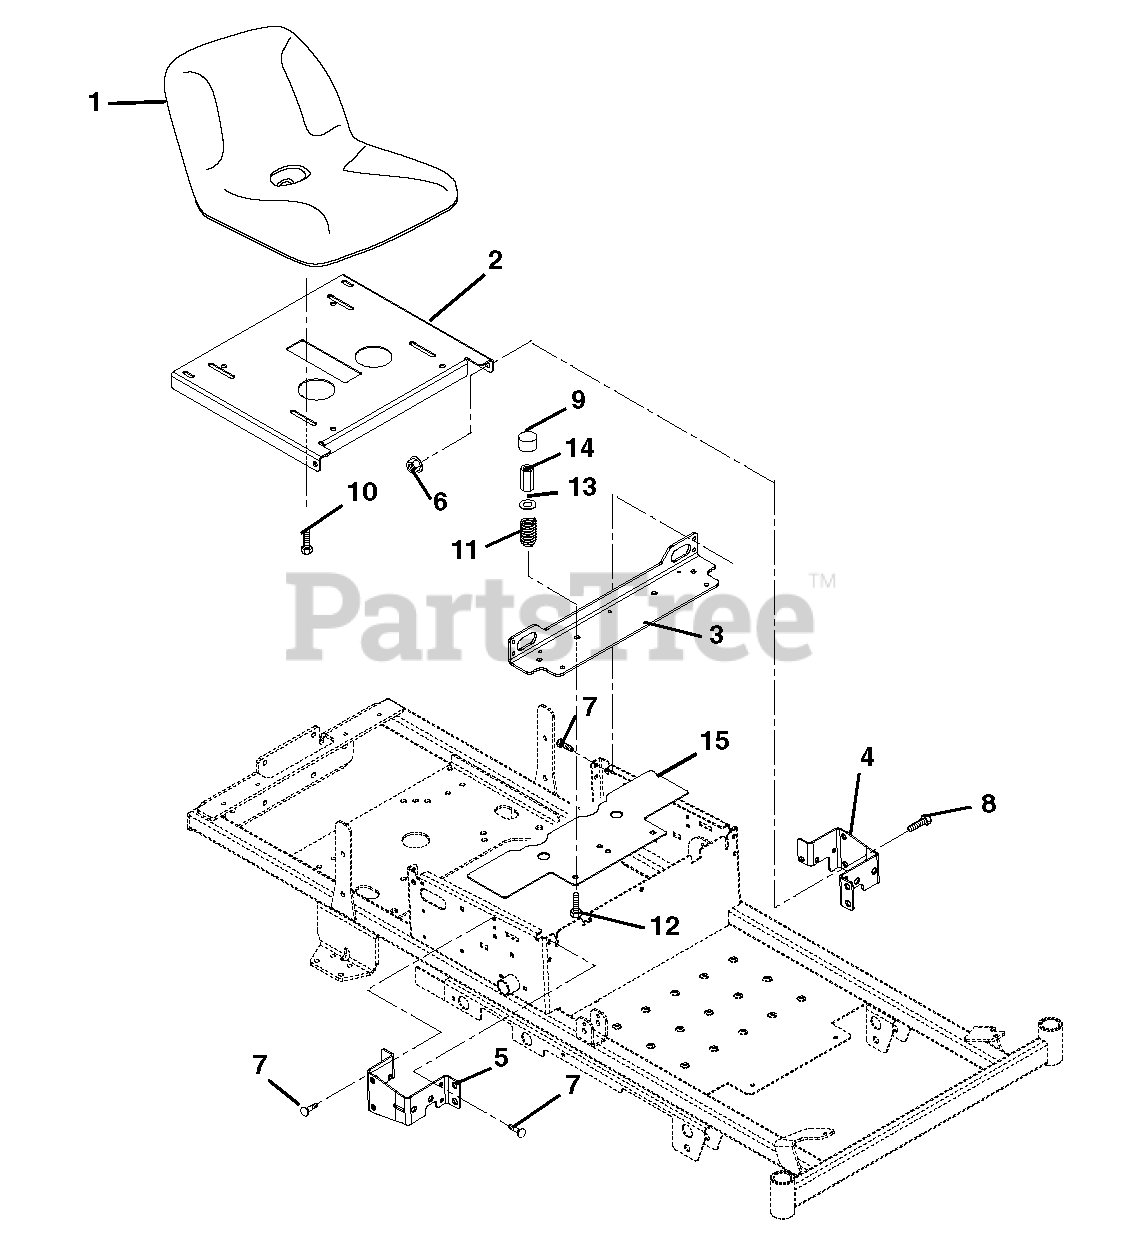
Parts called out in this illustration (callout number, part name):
1	Seat, Milsco XB150 Gray (100 - Serial No. 1148 and up; 102 - Serial No. 1013 and up; 104 - Serial No. 663 and up, 132 - Serial N
2	Seat Plate
3	Bracket, Seat Spring
4	Bracket, RH Steering Stop
5	Bracket, LH Steering Stop
6	Nut, Locking Flange .38-16
7	Screw, Tapping .31-18 x .50
8	Bolt, Shoulder .375-16 x 1.50
10	Bolt-Hex .31-18 x 1.00 Grade 5
11	Spring, Seat
12	Bolt, Round Head Square Neck .31-18 x 1.50 Grade 5
13	Washer-Flat-Steel .328 x .87 x .179
14	Nut, Coupling 5/16-18 x 1 .75
15	Guard, Finger
